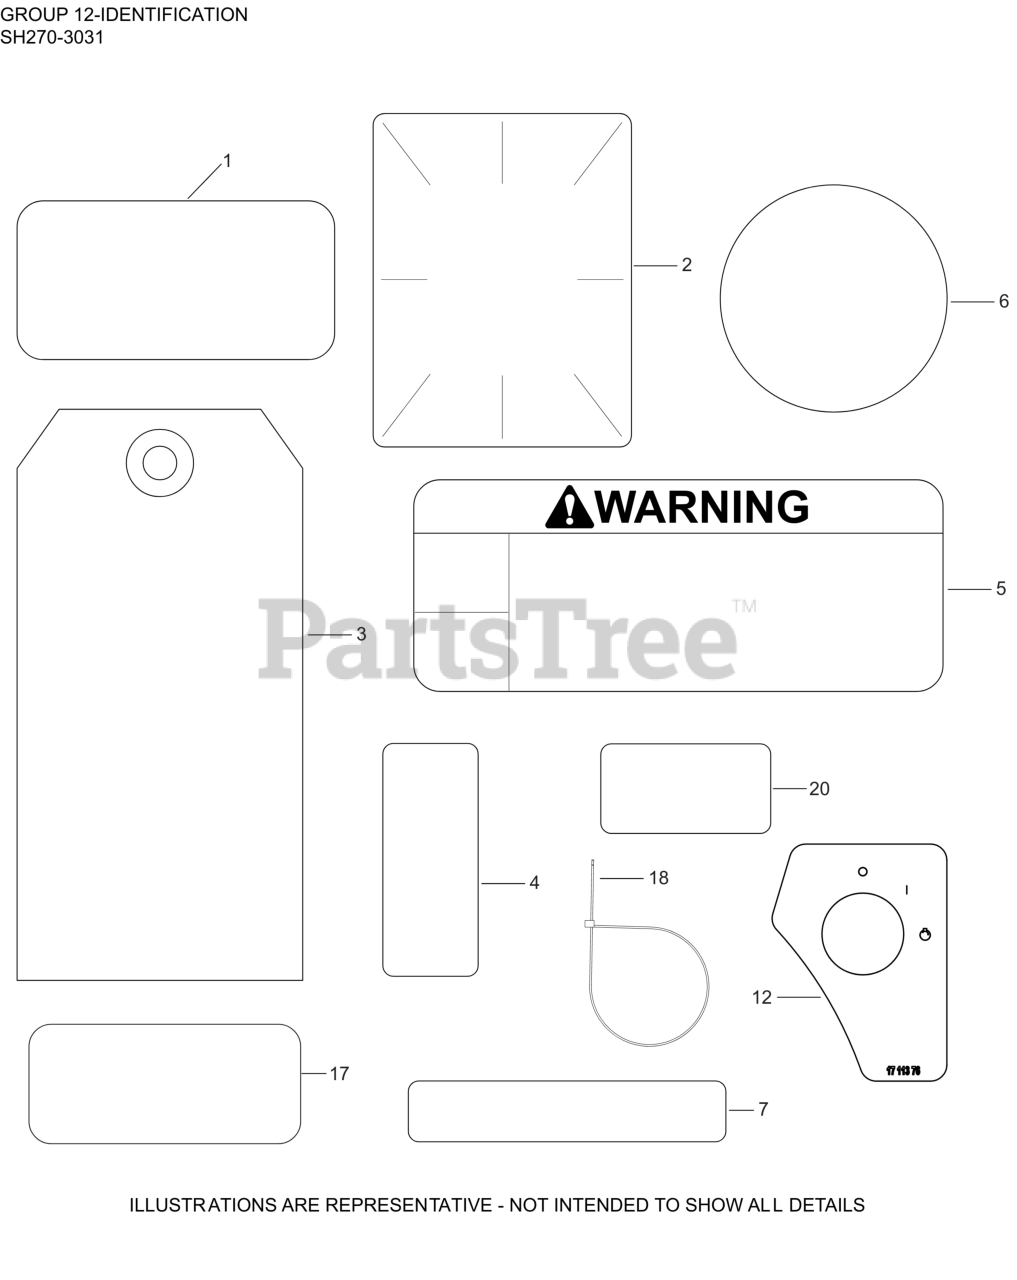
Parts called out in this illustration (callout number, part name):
1	LABEL, MAINTENANCE (CKY)
2	LABEL, CLEAR LAMINATION
3	TAG, HANG
3	TAG, PROP 65-OIL FILL ASSEMBLED
4	DECAL, FUEL/CHOKE - ON/OFF
5	DECAL, WARNING
6	LABEL, RECOIL 75MM
7	DECAL, THROTTLE
12	LABEL, KEY BOX
17	DECAL, ETHANOL WARNING
20	LABEL, HP SH270
